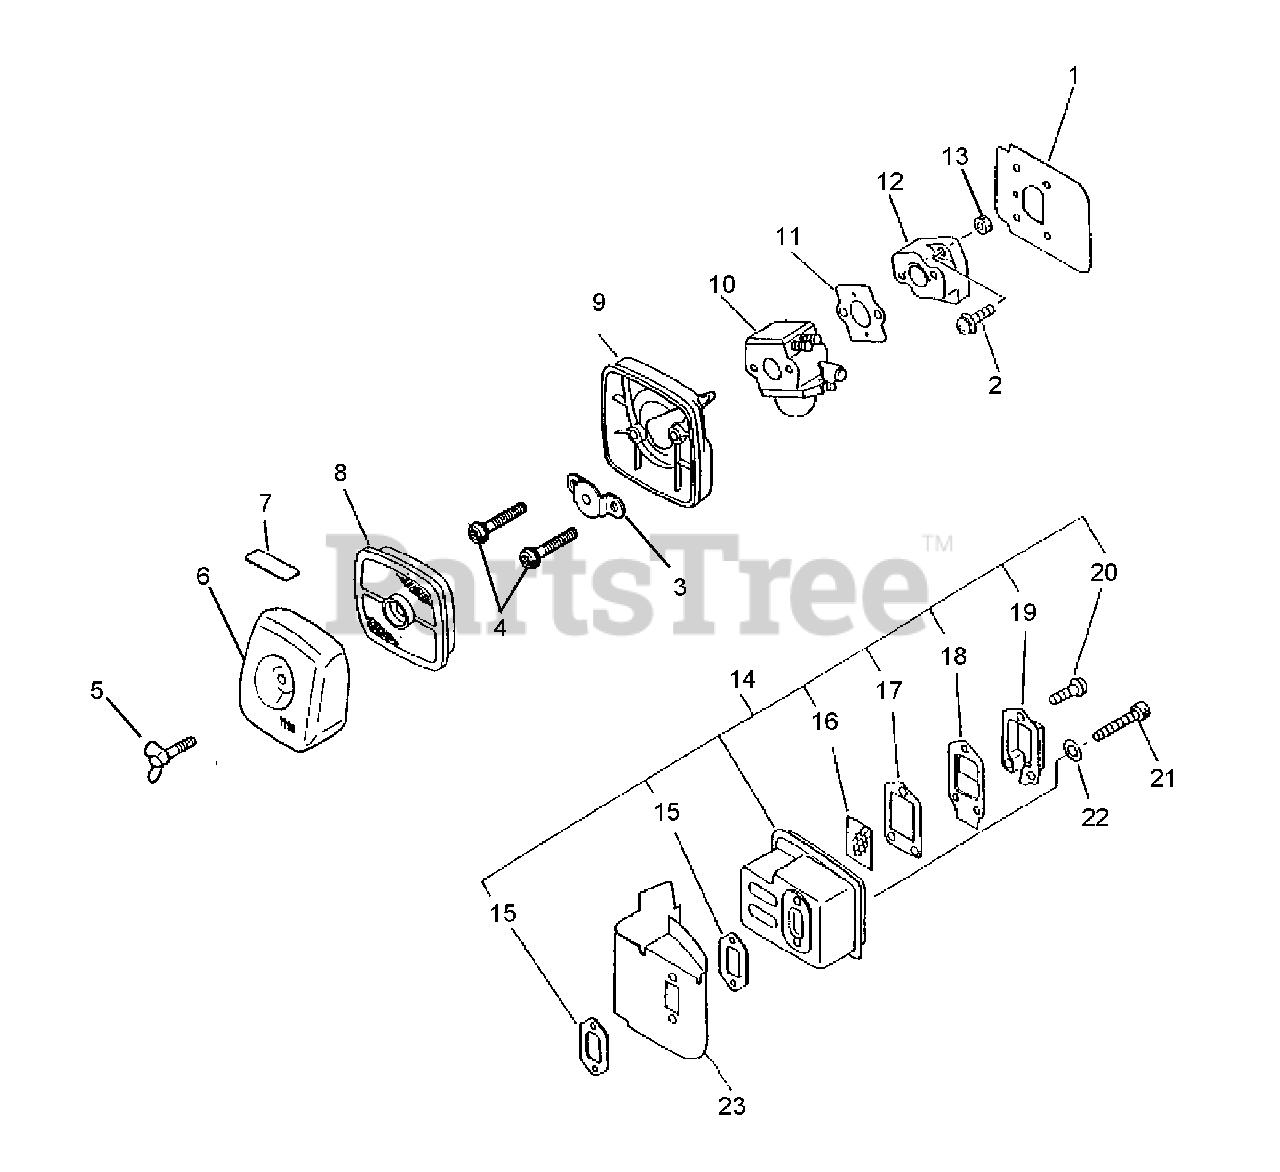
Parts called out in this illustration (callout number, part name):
1	SHIELD, INTAKE
2	SCREW - 5X20
3	PLATE, PREVENT
4	SCREW - 5X64
4	SCREW - 5X65
5	WINGNUT - 6
5	THUMBSCREW
6	COVER, AIR FILTER
6	COVER, AIR FILTER - BLACK
6	COVER, AIR FILTER - GRAY
7	LABEL - CHOKE
8	FILTER, AIR
8	FILTER, AIR - SINGLE LAYER
9	AIR FILTER CASE KIT - BLACK
9	AIR FILTER CASE ASSY
10	CARBURETOR WT-168A
10	CARBURETOR C1U-K18
10	CARBURETOR C1U-K35
10	CARBURETOR C1U-K51
11	GASKET, INTAKE
12	INSULATOR, INTAKE
14	MUFFLER ASSY
15	GASKET, EXHAUST
16	SCREEN, SPARK ARRESTOR
17	GASKET, EXHAUST
18	GASKET, EXHAUST - INNER
19	GUIDE, EXHAUST
19	GUIDE, EXHAUST - OUTER
20	SCREW - 4X10
21	SCREW - 5X55
22	WASHER - 5
23	SHIELD, EXHAUST
